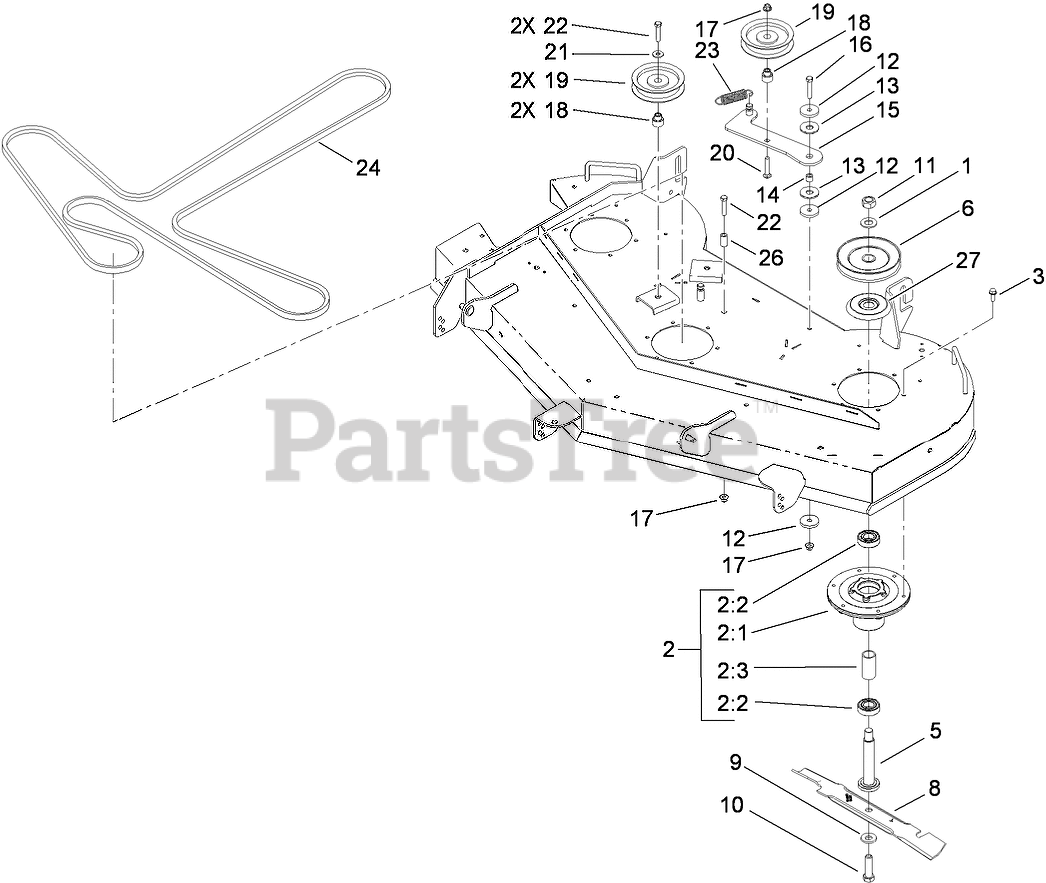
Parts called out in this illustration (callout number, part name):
1	WASHER
2	SPINDLE ASM
2:1	HOUSING-SPINDLE
2:2	BEARING-BALL
2:3	SPACER-BEARING
3	SCREW-TAPTITE
5	SHAFT-SPINDLE
6	PULLEY
8	BLADE-MULCH, 18.75 INCH
9	WASHER-BELLEVILLE
10	SCREW-BLADE
11	NUT-HEX
12	WASHER-PLAIN
13	WASHER-FRICTION, COMPOSITE
14	BUSHING-LEVER, LIFT
15	ARM-IDLER
16	SCREW-HH
17	NUT-HF, NI
18	BUSHING-IDLER
19	PULLEY-IDLER
20	SCREW-CARR
21	WASHER-HARDENED
22	SCREW-HH
23	SPRING-EXTENSION
24	V-BELT
26	SPACER
27	SHIELD-BEARING
